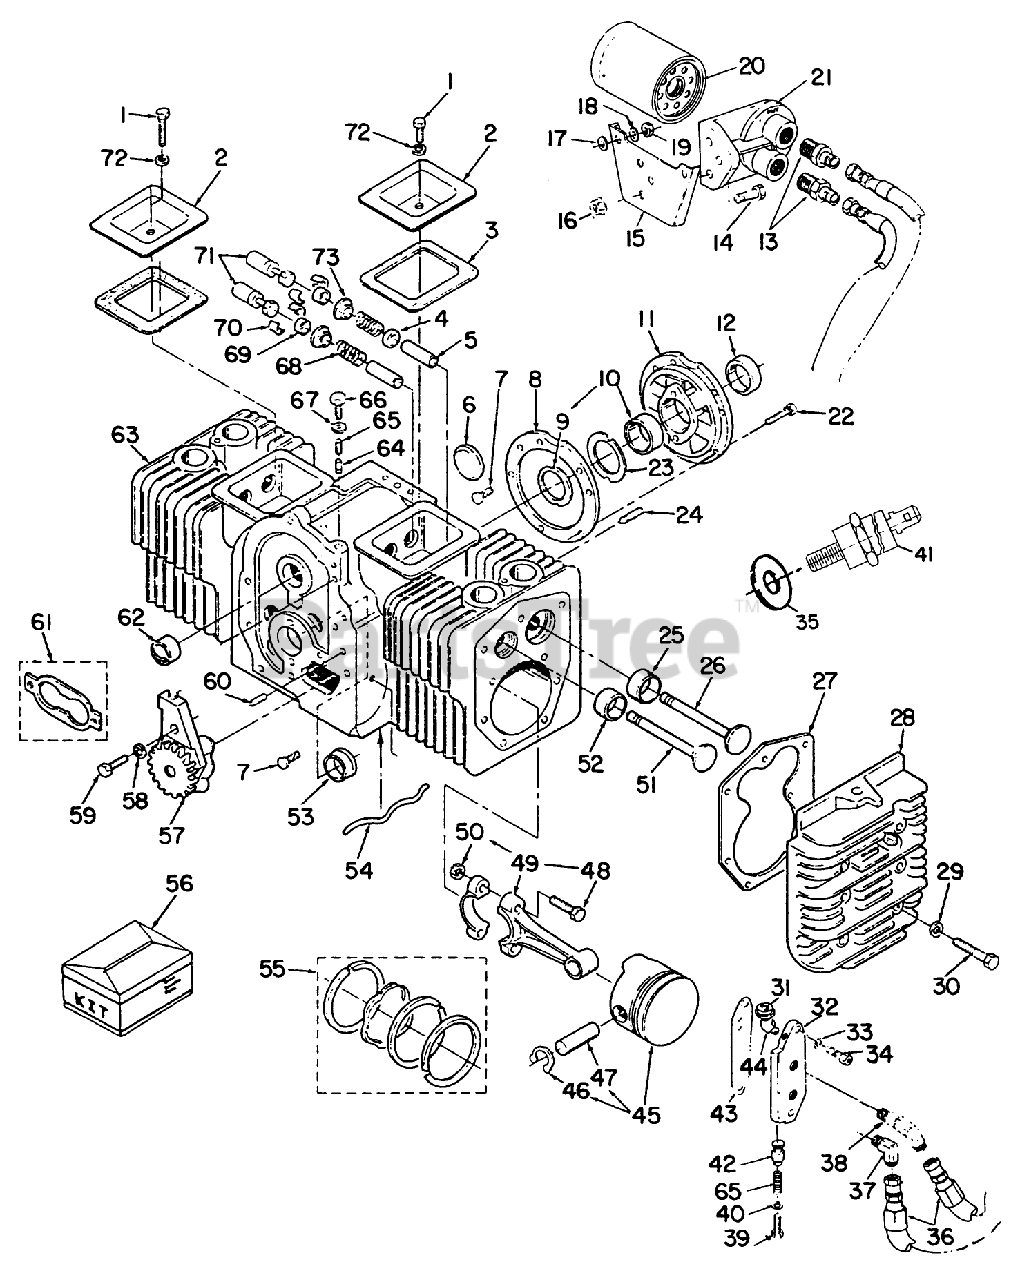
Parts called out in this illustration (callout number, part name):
1	SCREW-HH
2	Cover-Valve
3	GASKET
4	VALVE STEM SEAL
5	EXHAUST VALVE GUIDE
5	INTAKE VALVE GUIDE
7	PIN-DRIVE
8	GASKET
9	WASHER
10	Bearing-Std. Crankshaft (Incl. Ref. #9)
10	Bearing-Crankshaft .002" undersize (Incl. Ref. #9)
10	Bearing-Crankshaft .010" undersize (Incl. Ref. #9)
10	Bearing-Crankshaft .020" undersize (Incl. Ref. #9)
10	Bearing-Crankshaft .030" undersize (Incl. Ref. #9)
11	Plate-Bearing
13	MALE CONNECTOR
14	SCREW-HH
15	BRACKET
16	NUT-GEAR COVER
17	WASHER
18	WASHER
19	Nut
20	FILTER-OIL
21	BASE ASM
22	CAPSCREW
24	SCREW-SET
25	STD INSERT
25	Insert-Valve Seat .002" oversize
25	Plug-Breather Hole
25	INSERT .010
25	Insert-Valve Seat .025" oversize
26	INTAKE VALVE
27	GASKET KIT
28	Head-Cylinder R.H.
29	WASHER
30	CAPSCREW
31	SWITCH
32	Adapter,Oil Filter
33	WASHER
34	SCREW-HSH
35	WASHER-FLAT
36	Hose-Oil
37	MALE CONNECTOR
38	MALE CONNECTOR
39	SCREW-HH
40	WASHER
41	HI-TEMP CUT-OFF SWITCH
42	PLUNGER
43	Gasket
44	ELBOW-45 DEG
45	Piston-Std. (Incl. Ref. #46 & 47)
45	Piston-.005" oversize (Incl. Ref. #46 & 47)
45	Piston-.010" oversize (Incl. Ref. #46 & 47)
45	Piston-.020" oversize (Incl. Ref. #46 & 47)
45	Piston-.030" oversize (Incl. Ref. #46 & 47)
45	Piston-.040" oversize (Incl. Ref. #46 & 47)
46	Piston Pin
47	PISTON PIN
49	Rod-Connecting Std. (Incl. Ref. #48 & 50)
49	Rod-Conn. .010 undersize (Incl. Ref. #48 & 50)
49	Rod-Conn. .020 undersize (Incl. Ref. #48 & 50)
49	Rod-Conn. .030 undersize (Incl. Ref. #48 & 50)
51	EXHAUST VALVE
52	STD INSERT
53	KIT-BEARING, SLEEVE
53	BEARING-CRANKSHAFT
53	BEARING KIT (.010)
54	OIL TUBE
55	RING SET
55	Piston Ring Set .005" Oversize
55	Piston Ring Set .020" Oversize
55	RING SET .030 OS
55	Ring Set-Piston .040" oversize
56	ENGINE GASKET KIT
58	WASHER-LOCK
59	SCREW-HH
60	PIN-GEAR COVER
61	GASKET KIT
62	SLEEVE-BEARING
63	Block-Short
64	PLUNGER
65	Spring, Bypass
66	SCREW-HH
67	WASHER
68	VALVE SPRING
69	VALVE CAP
70	Lock-Valve Spring
71	TAPPET
71	TAPPET .002 OS
71	.005" Oversize
72	WASHER
73	VALVE SPRING RETAINER
